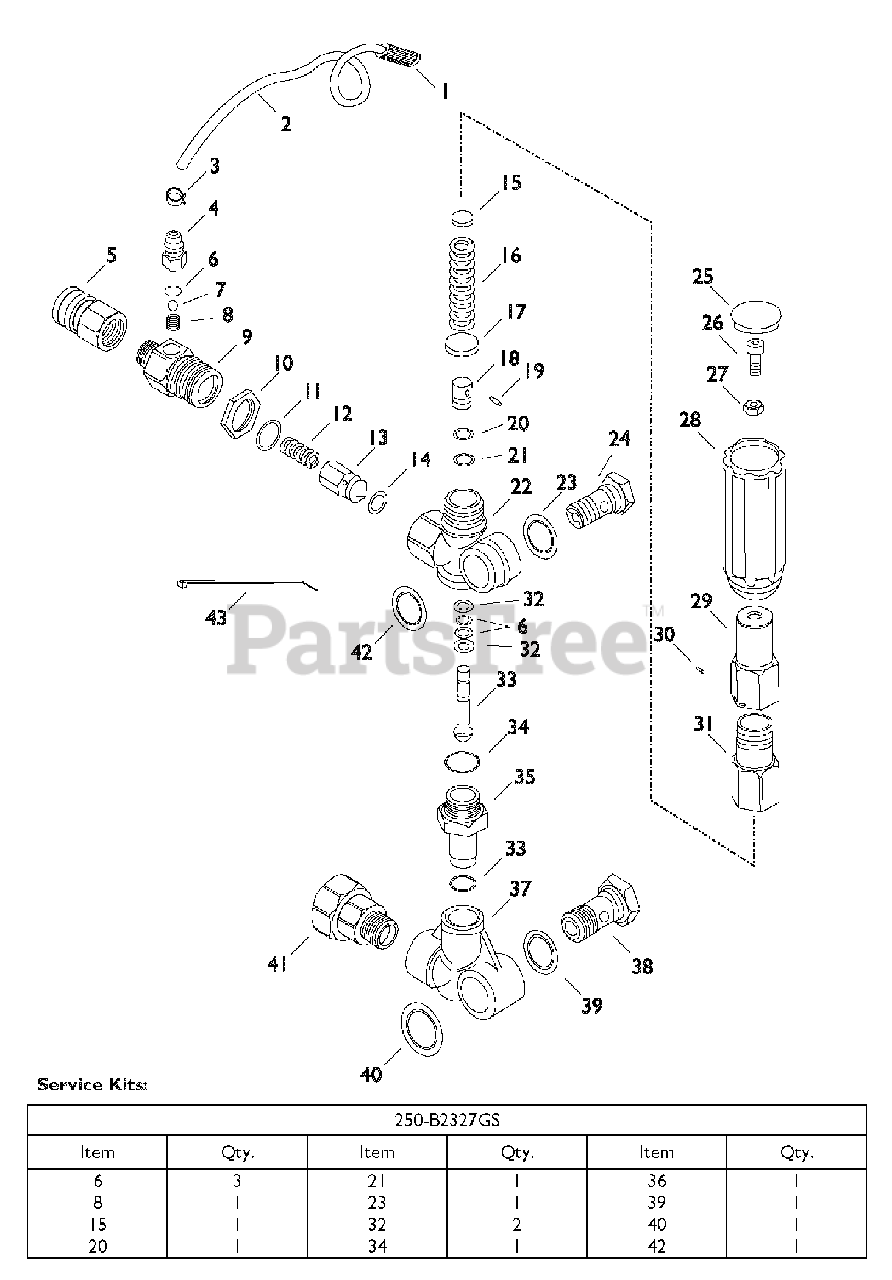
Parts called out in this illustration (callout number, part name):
1	Filter, Chem
2	Hose, Chem
3	Clamp, Hose band
4	Hose Tail
5	Quick Disconnect
6	O-Ring
7	Stainless Ball
9	Injection Body
10	Injector Nut
15	Spacer Plate
17	Spring, Spacer Plate
18	Upper Piston
22	Valve Housing
24	Inlet Bolt
31	Spring Guide
33	Lower Piston
35	Piston Guide
37	Bypass Fitting
38	Inlet Bolt
41	Connector, Garden Hose
43	Wrap, Tie
